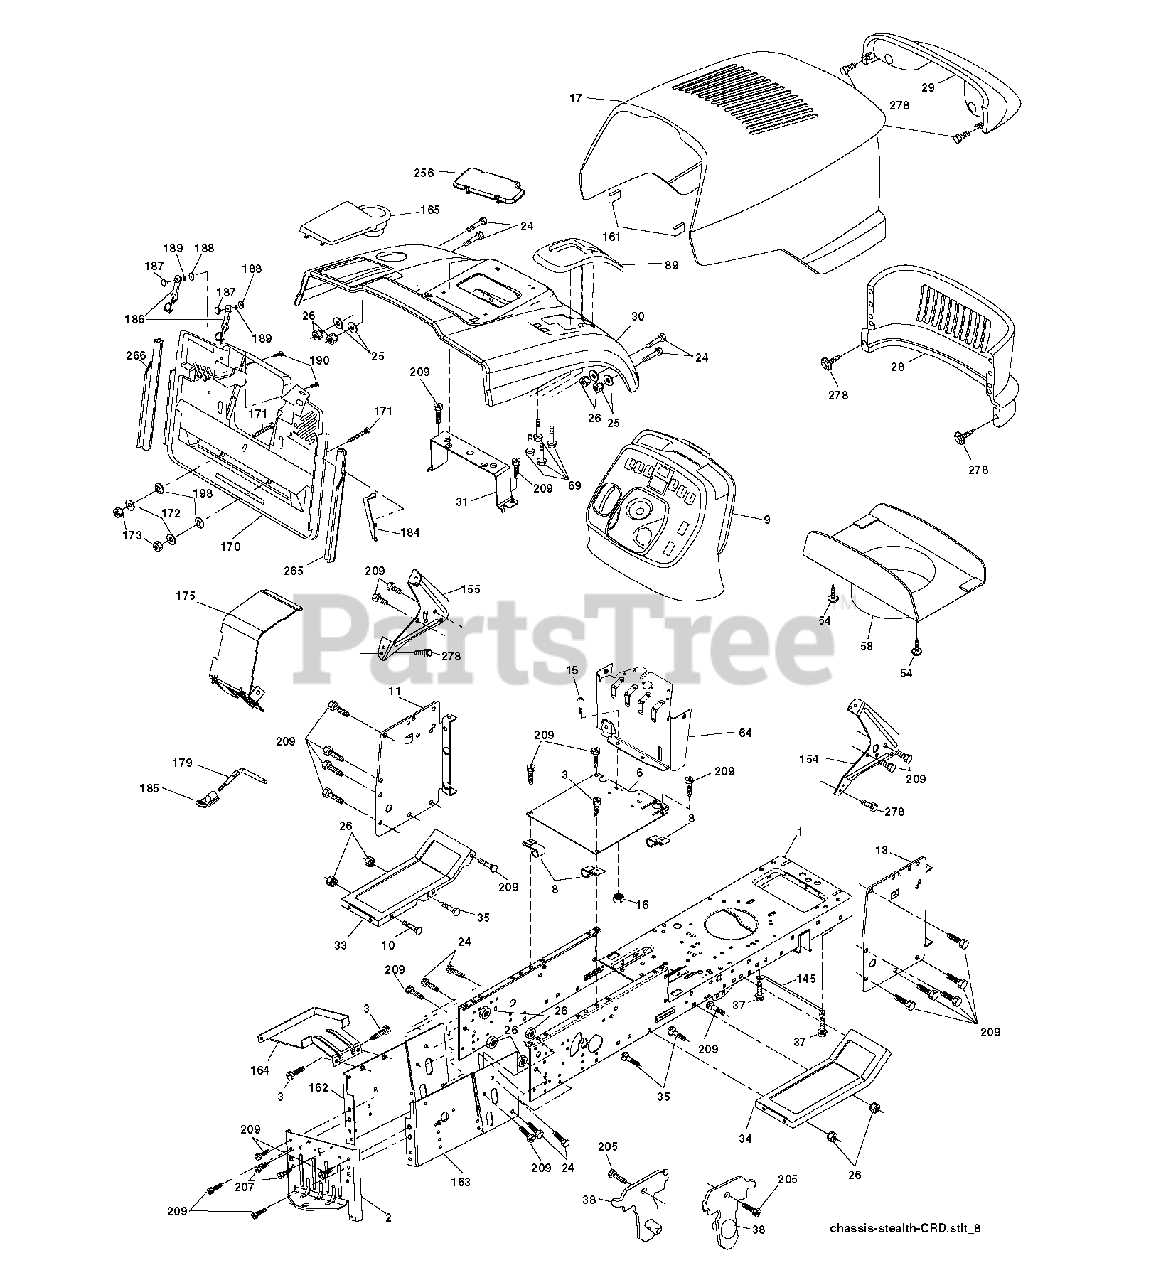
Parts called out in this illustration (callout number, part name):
1	CHASSIS
3	SCREW 3/8-16X3/4
8	CLIP,INSULATOR
10	BOLT D
13	PANEL DASH RH
16	NUT
25	WASHER
26	NUT
31	BRACKET SUPPORT FENDER
54	SCREW.WSHD.HEX10-32X5/8
58	DUCT HOOD
69	SCREW.HI-LO.CONSOLE
145	ROD.PIVOT.HOOD
161	EXTRUSION BUMPER
164	SUPPORT
171	BOLT
172	WASHER
186	LATCH ASSY
187	WELDNUT
189	LOCKWASHER
207	SCREW, 5/16-18 X 1/2
209	SCREW, 3/8-16X3/4
278	SCREW.#10 X 0.750.BOS THREAD
